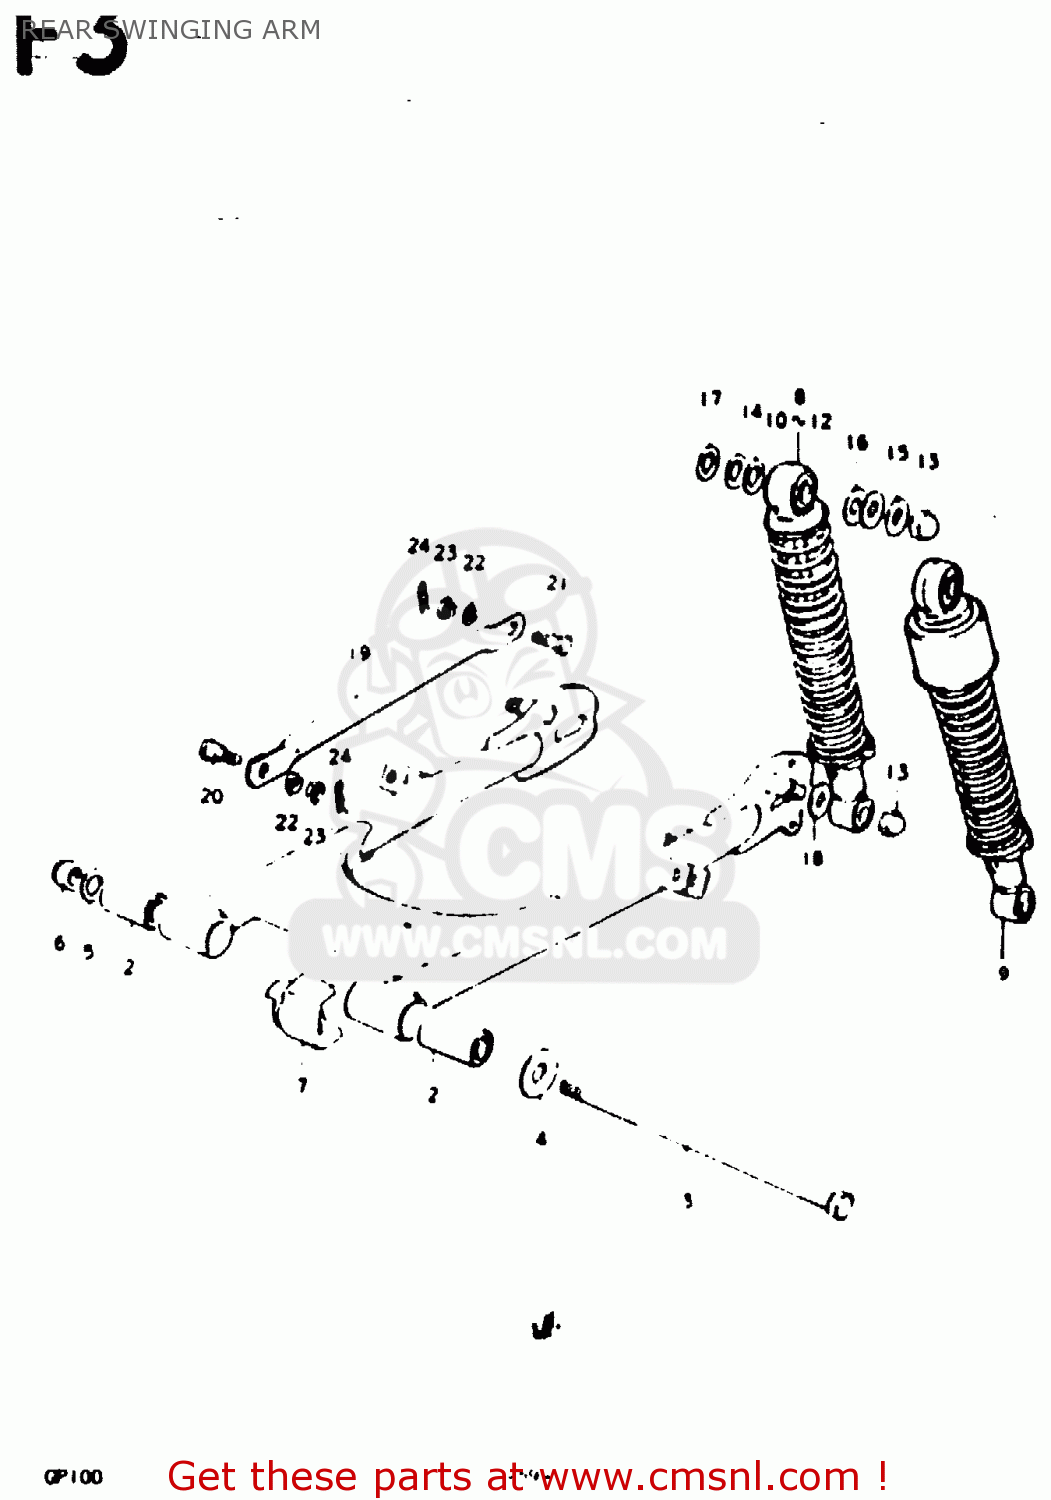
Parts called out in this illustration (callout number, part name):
1	SWINGING ARM SET, REAR (BLACK)
2	BUSH(12X24X44)
3	SHAFT,REAR SWING ARM
4	WASHER(12.5X32X2.3)
5	WASHER
6	NUT
7	BUFFER,CHAIN TOUCH DEFENSE
8	ABSORBER ASSY, REAR SHOCK
13	NUT, LOWER LH
14	WASHER
15	WASHER
16	WASHER(10.5X24X3.2)
17	WASHER (12.5X24X3.2)
19	TORQUE LINK, REAR
20	BOLT(8X22.5)
21	BOLT(8X26.5)
22	LOCK WASHER
23	NUT
24	CLIP
